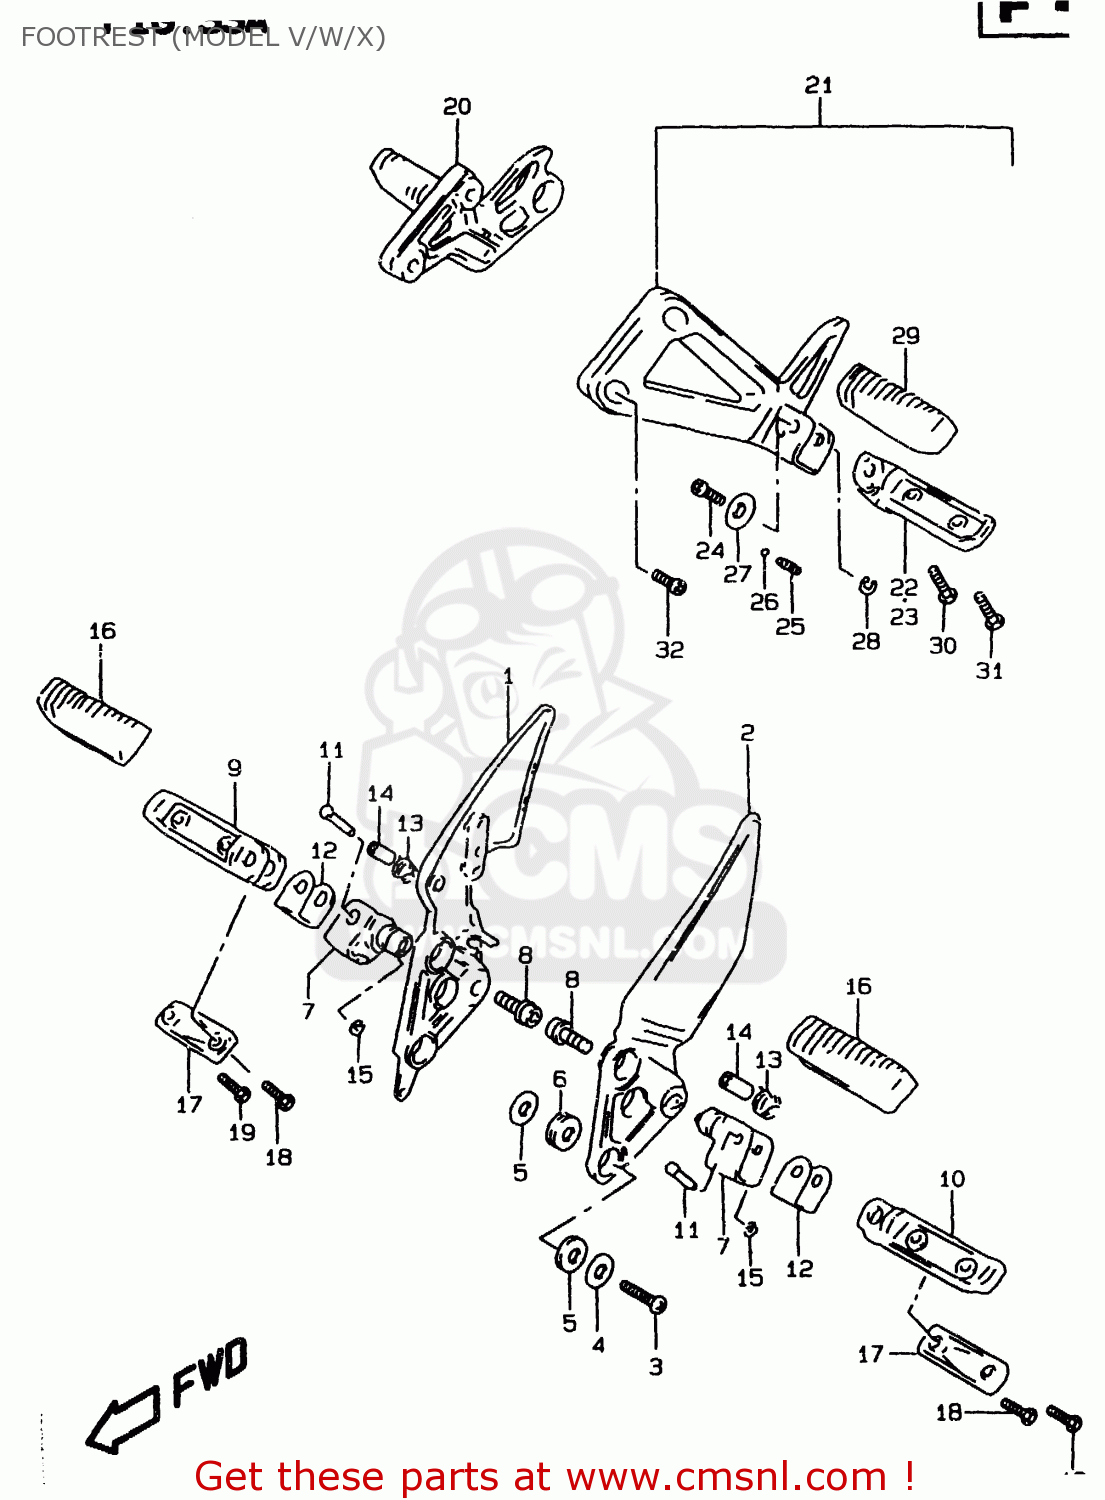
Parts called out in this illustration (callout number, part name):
1	BRACKET,FRONT FOOTREST
2	BRACKET,FRONT FOOTREST
3	BOLT(8X28)
4	WASHER (8.5X24X1.6)
5	WASHER(12.6X24X1.9)
6	BUSH(12X20X16)
7	HOLDER,FOOTREST
8	BOLT(10X28)
9	BAR,FOOTREST,R
10	BAR,FOOTREST,L
11	PIN(8X33.2)
12	CUSHION,FR FOOTREST
13	SPRING
14	SPACER(8.1X12X22)
15	E.RING
16	RUBBER,FOOTREST
17	BALANCER,FR FOOTREST
18	SCREW
19	SCREW
20	FOOTREST ASSY,PILLION,R
21	FOOTREST ASSY,PILLION,L
22	BAR,PILLION FOOTREST,R
23	BAR,PILLION FOOTREST,L
24	BOLT,PILLION FOOTREST
25	SPRING
26	BALL
27	WASHER(10.5X24X1.6)
28	E.RING
29	RUBBER,FOOTREST
30	SCREW 5X20
31	SCREW
32	BOLT(8X25)
